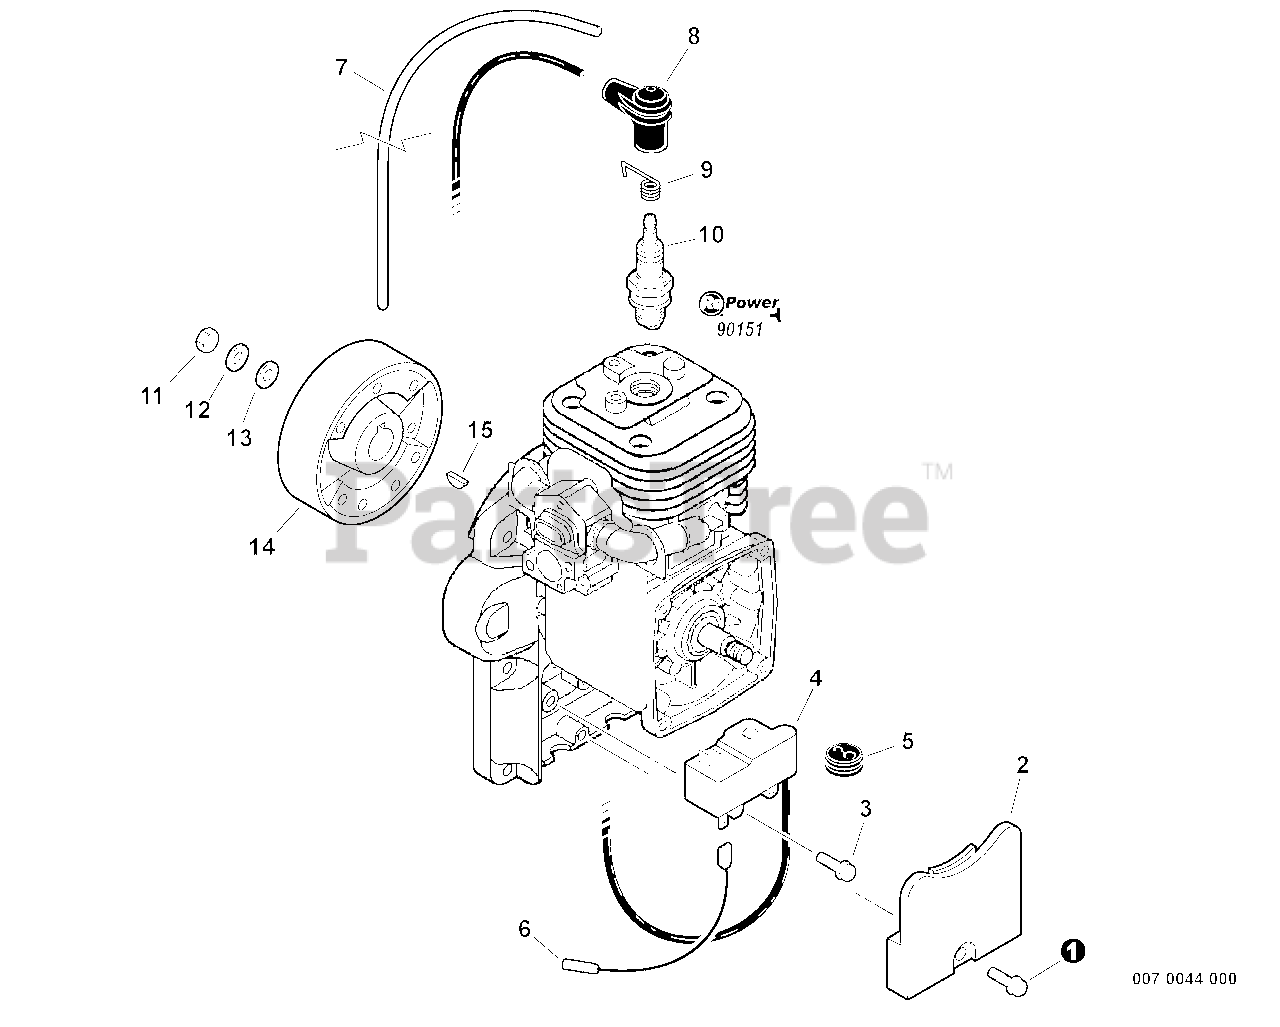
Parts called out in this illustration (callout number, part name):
1	SCREW - 5X18
2	COVER, DUST
3	SCREW - 5X18
4	COIL, IGNITION
6	LEAD - IGNITION
7	TUBE - VINYL
8	CAP, SPARK PLUG
9	TERMINAL, SPARK PLUG CAP
10	SPARK PLUG -- BPM-8Y
10	SPARK PLUG -- BPMR-8Y
11	NUT - 10
12	LOCKWASHER - 10
13	WASHER - 10
14	FLYWHEEL
15	KEY - 3X14
16	RePower TUNE-UP KIT
